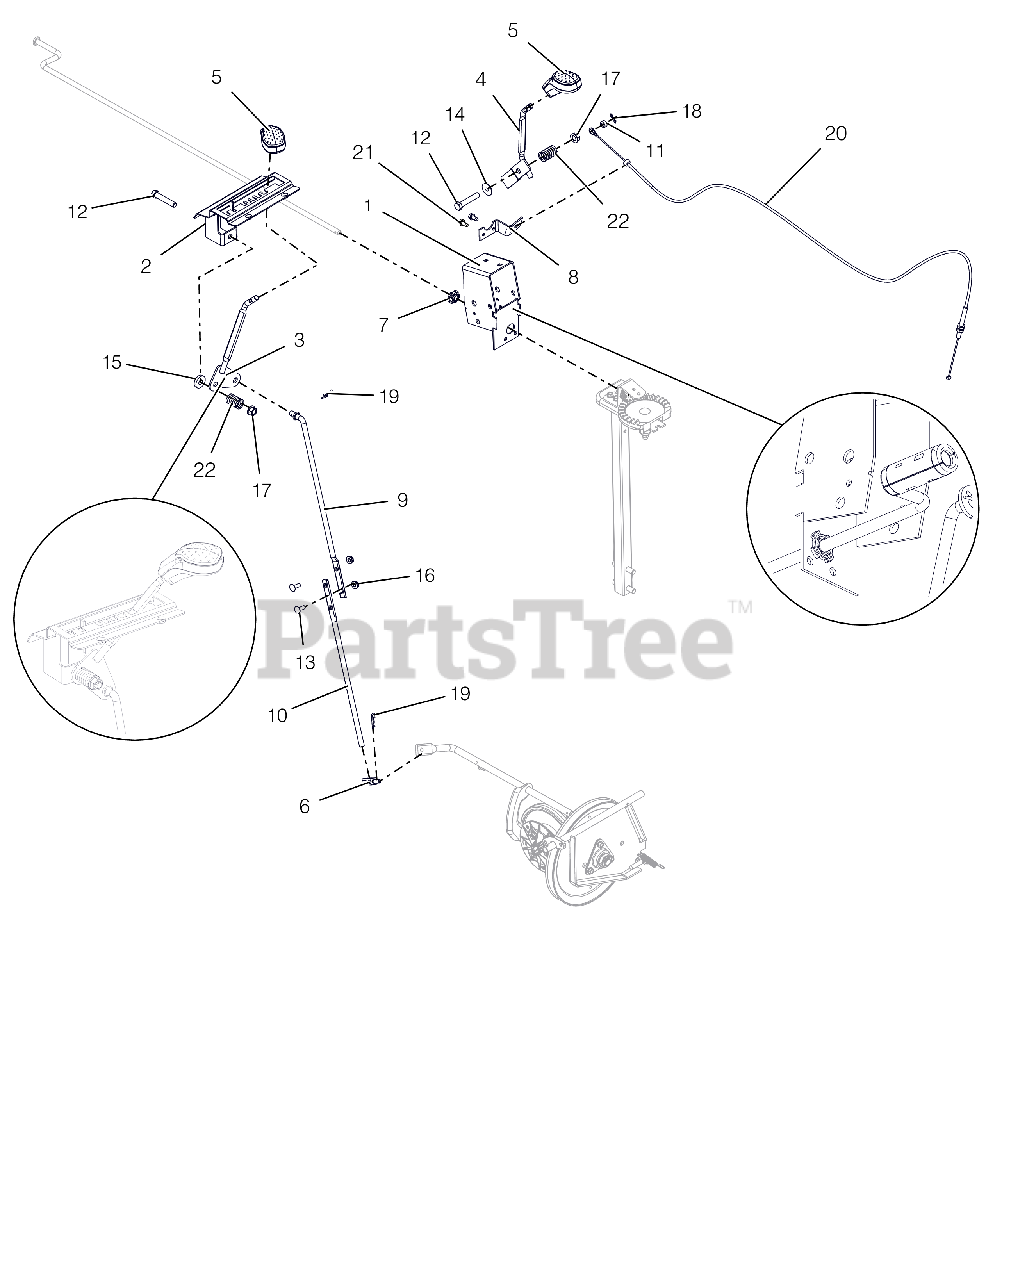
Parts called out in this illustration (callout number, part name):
1	WELDMENT, BRACKET INTERLOCK
2	WELDMENT, DETENT PLATE-COMPACT
3	LEVER, CONTROL-SHIFT(WELDMENT)
4	WELDMENT,SM DASH DEFL CONTROL
5	KNOB, CONTROL, DASH
6	PIVOT,SHIFT ROD .375-16(TRUNN)
7	CRANK BUSHING, NYLON CHUTE BK
8	ANCHOR, DEFLECTOR CABLE
9	ROD, SHIFT - UPPER
10	ROD, SHIFT - LOWER(SMALL DASH)
11	BSHG-SLV .265X.500X.219
12	@BLT-HEX .38-16X2.00 GR5 YWZC
13	@BLT-RDHDSQNK .25-20X.75 G5YZ
14	WSHR-FL-STL .281X1.000X.063
15	WSHR-FL-STL .406X1.00X.188 YWZ
16	@NUT-LK-CTR-FLG .25-20 YWZC
17	@NUT-LK-TOP-FLG .38-16 YWZC
18	PIN-HAIR INT .06X.18X.77
19	PIN-HAIR INT .08X.18X1.18 YWZC
20	CABLE, DEFLECTOR - COMPACT
21	SCR-TAP .25-20X.50 HWH TR YWZ
22	SG-COMP .125X.781X1.250
